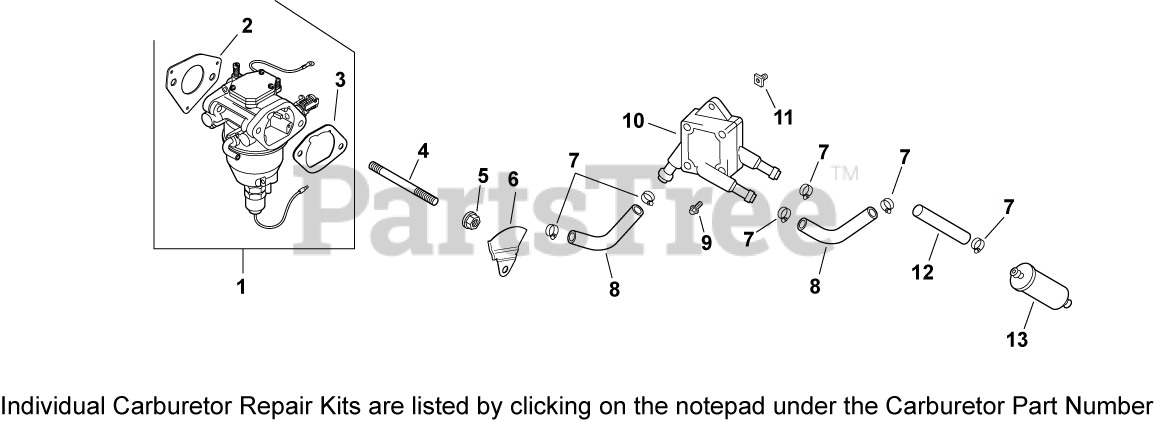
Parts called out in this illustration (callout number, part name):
1	CARBURETOR KIT-USE 24 853 169-S
2	GASKET, CARBURETOR
3	GASKET, AIR CLEANER BASE
4	STUD,M6X1.0X96
5	NUT, FLG M6X1.0
6	BAFFLE, SPIT-BACK CUP-USE 24 063 105-S
7	CLAMP, HOSE (KM)-USE 25 237 31-S
8	HOSE,LW PERM.FUEL 24.00"-USE 25 111 81-S
9	SCREW, TAP M6X1.7X18
10	PUMP, FUEL
11	NUT, PLASTIC (KM)-USE 25 100 37-S
12	LINE, FUEL 11"
13	FILTER, FUEL (9-12 MICRON)-USE 24 050 13
2485390-S	KIT, CARBURETOR w/GASKETS
